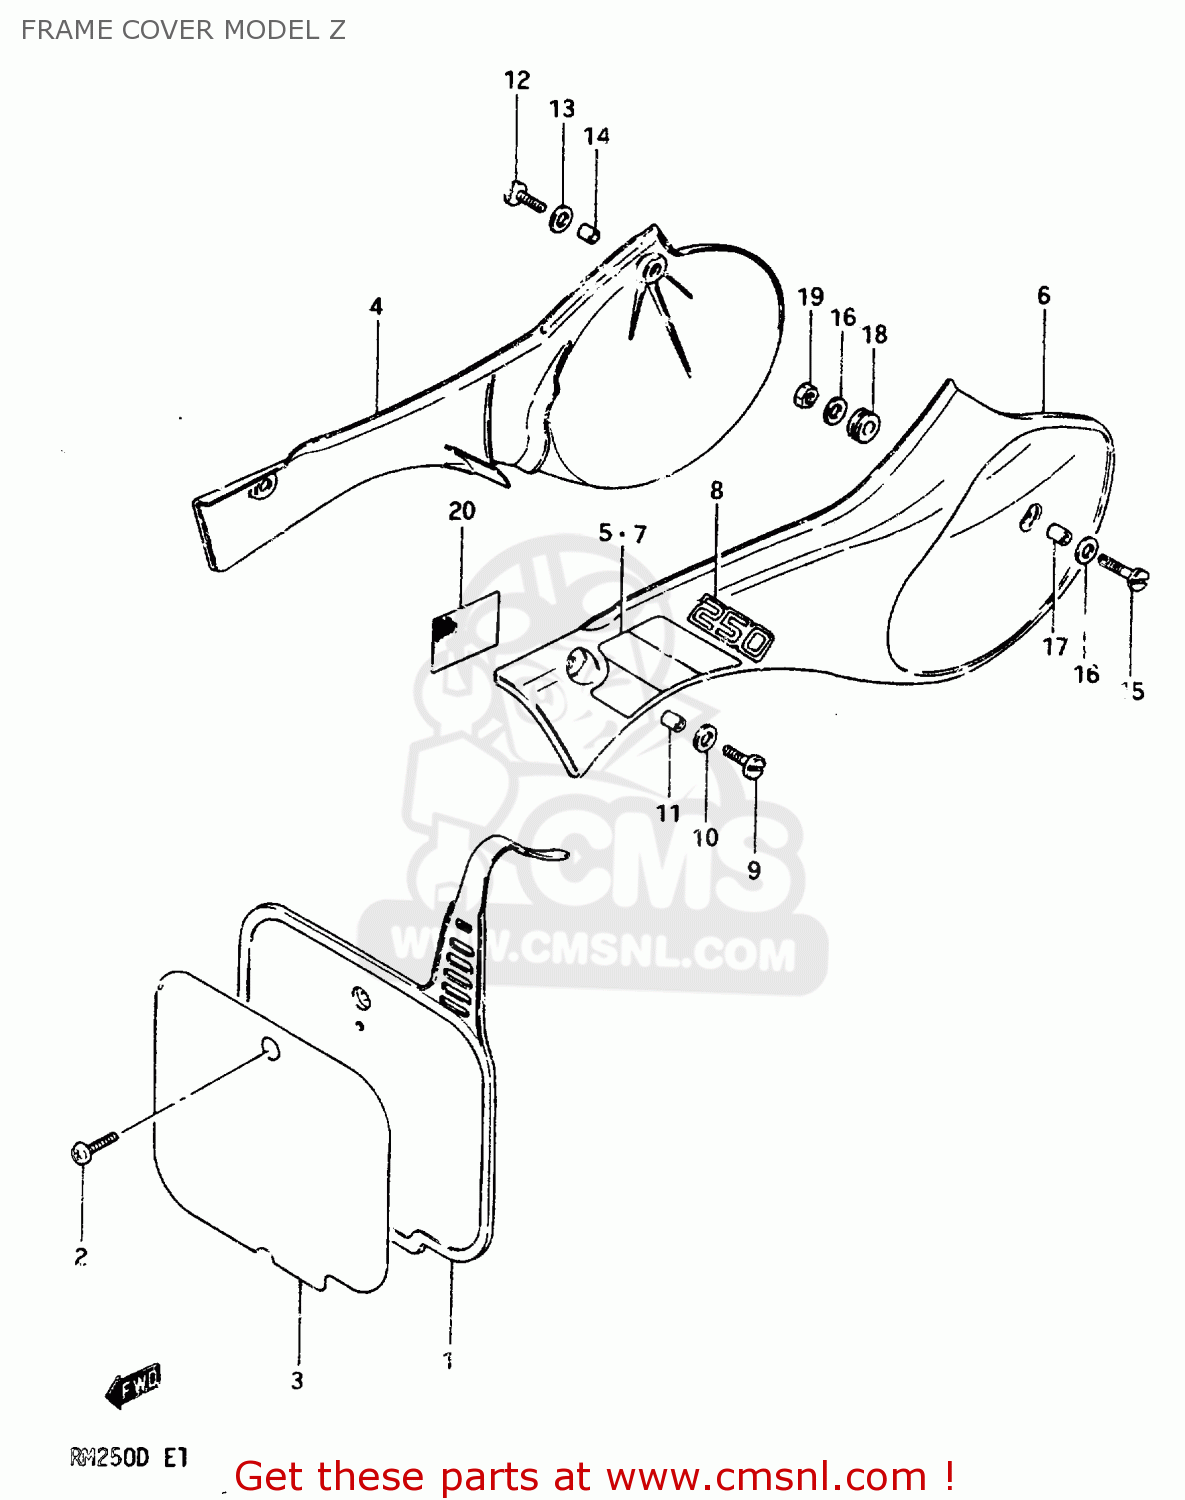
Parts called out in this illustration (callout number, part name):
1	PLATE,NUMBER,FRONT
2	SCREW
3	EMBLEM,FRONT NUMBER PLATE
4	COVER,FRAME,R(YELLOW)
5	TAPE,FRAME COVER,RIGHT
6	COVER,FRAME,LEFT
7	TAPE,FRAME COVER,LEFT
8	EMBLEM (250)
9	SCREW(6X25)
10	WASHER FRAME COVER
11	SPACER,FRAME COVER,FRONT
12	SCREW
13	WASHER FRAME COVER
14	SPACER FRAME COV RR
15	SCREW
16	WASHER FRAME COVER
17	SPACER,FRAME COVER,FRONT
18	CUSHION
19	NUT 6MM
20	HEAT SHIELD,FRAME COVER
